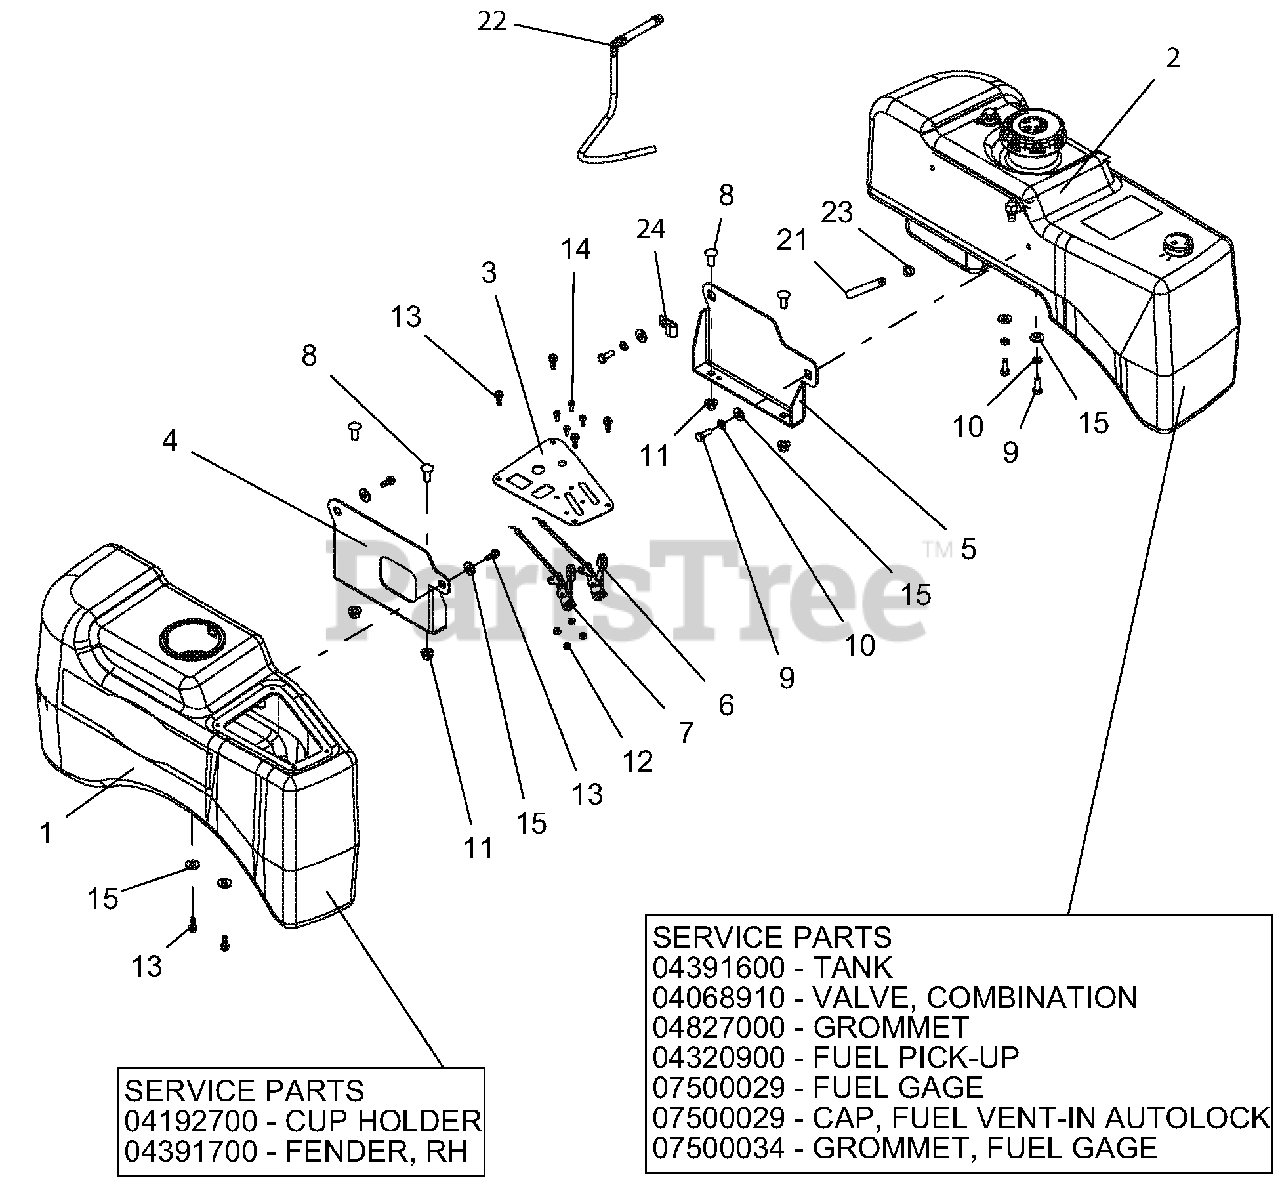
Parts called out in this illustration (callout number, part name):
1	ASM, FENDER W/CUPHOLDER
1	CUP HOLDER
1	FENDER, RH
2	HD, FUEL TANK ASSEMBLY
2	TANK
2	VALVE, COMBINATION
2	FUEL PICK-UP
2	FUEL GAGE
2	CAP, FUEL VENT-IN AUTOLOCK
2	GROMMET, FUEL GAGE
3	PANEL, INSTRUMENT-BLACK
4	BRKT, RH HD FUEL TANK MTG-RED
5	BRKT, LH HD FUEL TANK MTG-RED
6	CABLE, CONTROL
7	CABLE, CONTROL
8	BLT-RDHDSHSQNK.38-16X1.0 G5YZ
9	BLT-HEX .31-18X.875 GR5 YWZC
10	WSHR-LK .31X.078 REG YWZC
11	NUT-LK-NYL-FLG .38-16 YWZC
12	NUT-LK-NYL #10-24 YWZC
13	SCR-PLASTITE .25-10X.75 YWZC
14	@SCR-MCH 10-24X.50 HWH YWZC
15	WSHR-FL-STL.38X.875X.083 YWZC
21	.25 LOW-PERM GAS HOSE 27.50" LG - TANK TO ENGINE
22	ASM, PTS BRIGGS FUEL TANK VENT HOSE
23	CLAMP, FUEL LINE
24	CLAMP, J
